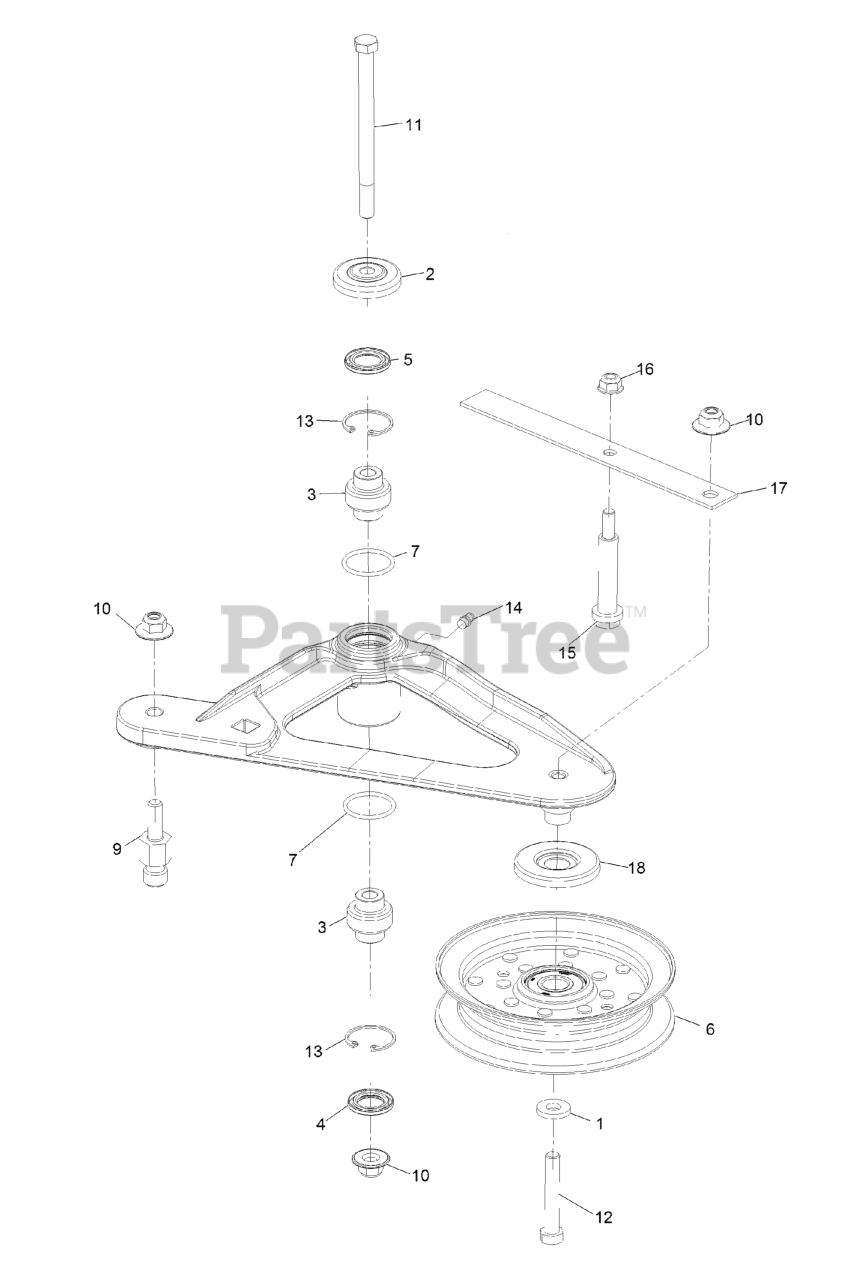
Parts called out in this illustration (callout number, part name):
2	GUARD-TOP
3	BEARING-SPHERICAL
4	SEAL-LIP, DOUBLE
5	SEAL-LIP, SINGLE
6	IDLER-PULLEY, FLAT
9	PIN-SPRING, ANCHOR
10	Nut-Nyloc 3/8-16 Flg
11	SCREW-SHOULDER, HH
12	SCREW-HH
13	RING-SNAP
14	FITTING-GREASE
15	BOLT-SHOULDER
16	NUT-HF, NI
17	SPRING-BELT
18	SHIELD-GUARD, DUST
